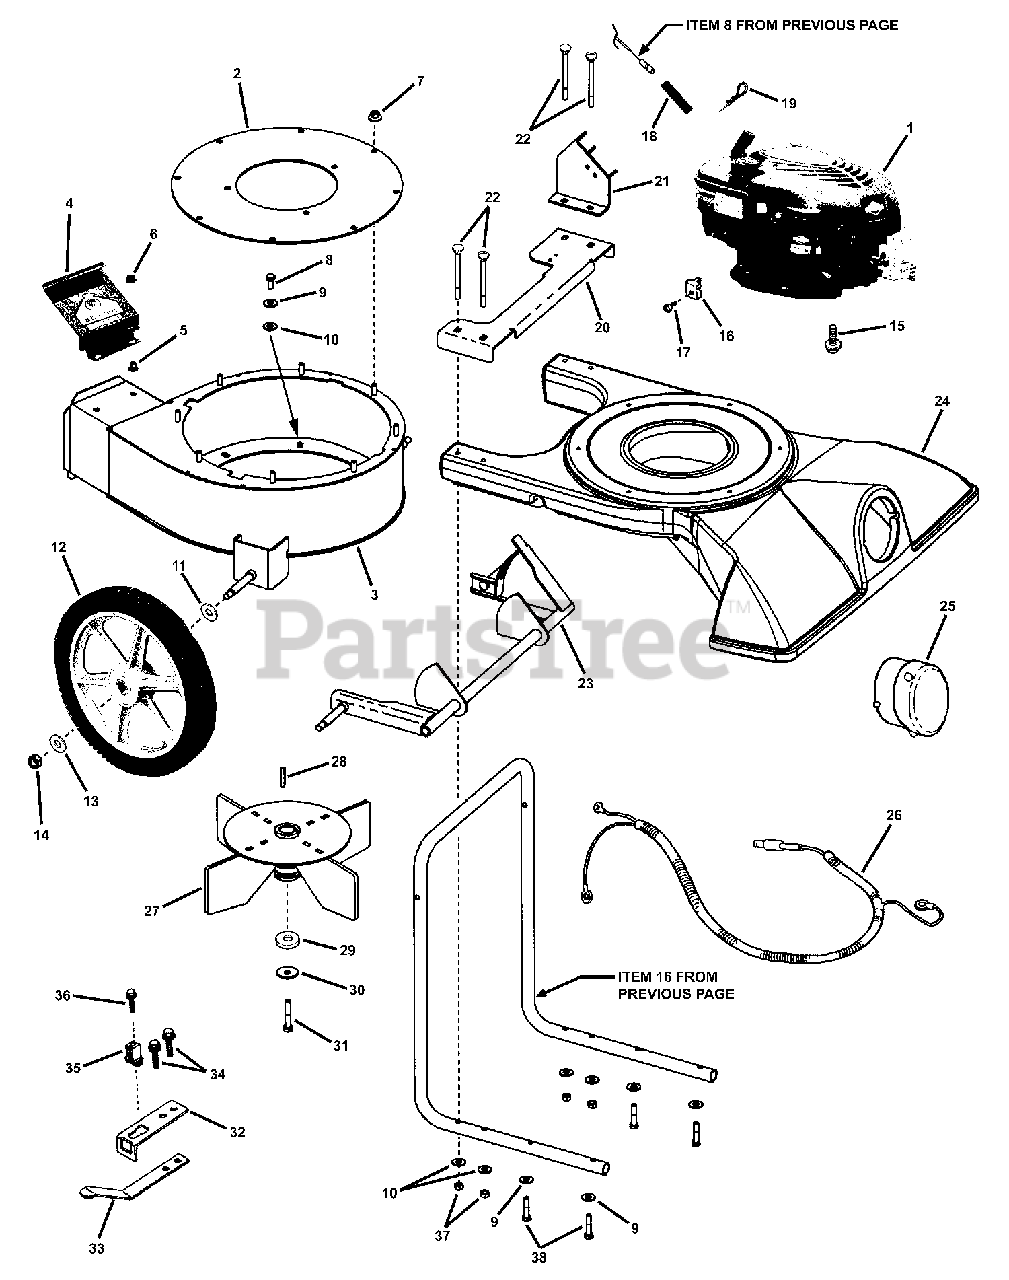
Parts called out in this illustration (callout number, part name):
1	* ENGINE, 6.5HP B&S Quantum Modular XRM, Recoil Start
2	PLATE, Engine Base Vacuum Universal
3	WELDMENT, Upper Housing
4	ASSEMBLY, Hinge Door
5	BOLT, 1/4-20 x 1/2" Short Neck Carriage, GR5
6	NUT, 1/4-20 Hex Flange Lock
7	NUT, 5/16-18 Hex Flange Lock, GR5
8	SCREW, 5/16-18 x 3/4" Hex Head Cap, GR5
9	WASHER, 5/16" Split Lock
10	WASHER, 5/16" Flat
11	WASHER, 1/2" Wave
12	WHEEL ASSEMBLY, 14.00 x 2"
13	WASHER, 3/8" SAE Flat
14	NUT, 3/8-16 Nyloc
15	SCREW, 3/8-16 x 1" Hex Washer Self-Tap
16	CLAMP, Casing
17	SCREW, #10-32 x 5/8" Hex Head Self-Tap
18	SPRING, Compression
19	HAIRPIN, 29/32" Cotter
20	PLATE, Reinforcing
21	WELDMENT, Cable Anchor
22	BOLT, 5/16-18 x 3-1/2" Short Neck Carriage, GR5
23	WELDMENT, Axle Ass'y, Drag Link
24	HOUSING, Lower
25	PLUG, Hose Port
26	WIRE HARNESS, Interlock
27	WELDMENT, Impeller
28	KEY, 1/4" Square x 1-7/16" long
29	WASHER, .468 I.D. x 1-5/8" O.D. x 1/4" thick
30	WASHER, Cone
31	SCREW, 3/8-24 x 2" Hex Head Cap, GR5
32	BRACKET, Interlock
33	SPRING, Interlock
34	SCREW, 1/4-20 x 1/2" Hex Washer Self-Tap
35	INSULATOR
36	SCREW, # 8-18 x 3/4 Sheet Metal
37	NUT, 5/16-18 Hex Nyloc
38	SCREW, 5/16-18 x 1-1/2" Hex Head Cap, GR5
